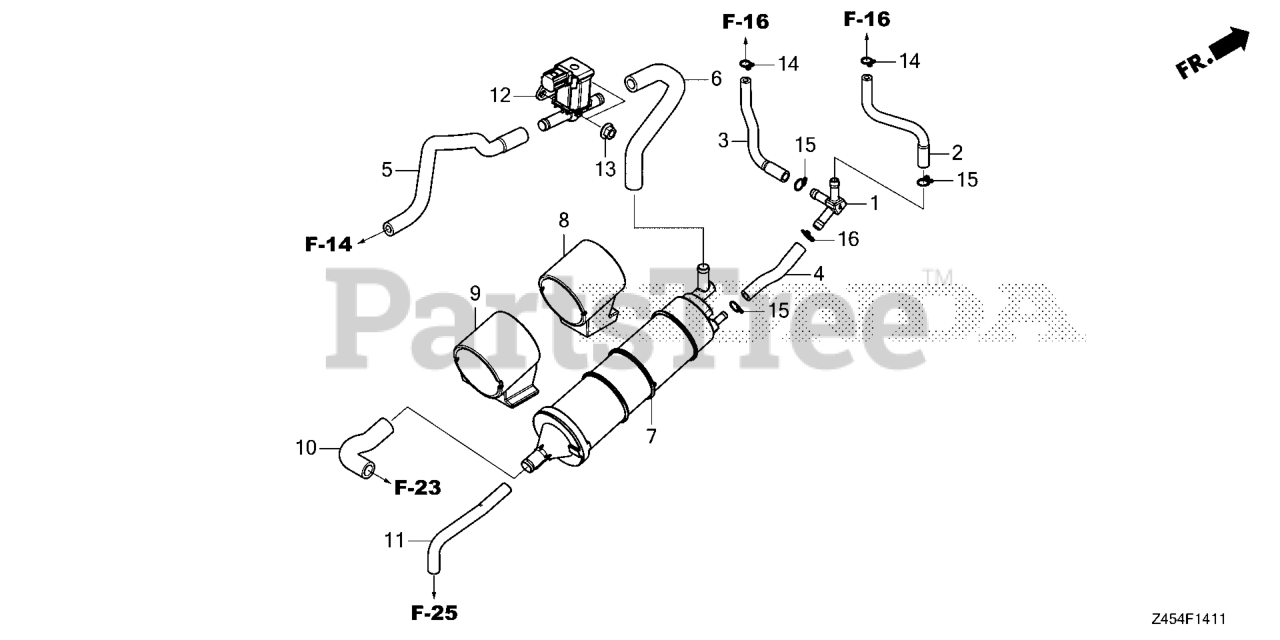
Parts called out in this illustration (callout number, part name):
1	JOINT, PIPE (3WAY)
7	CANISTER COMP
8	RUBBER A, CANISTER
9	RUBBER B, CANISTER
10	TUBE, CANISTER AIR
11	TUBE, CANISTER DRAIN
12	VALVE, PURGE CONTROL SOLENOID
13	NUT, FLANGE (5MM)
14	CLIP, TUBE (B7)
15	CLIP, TUBE (B8)
16	CLIP, TUBE (C9)
